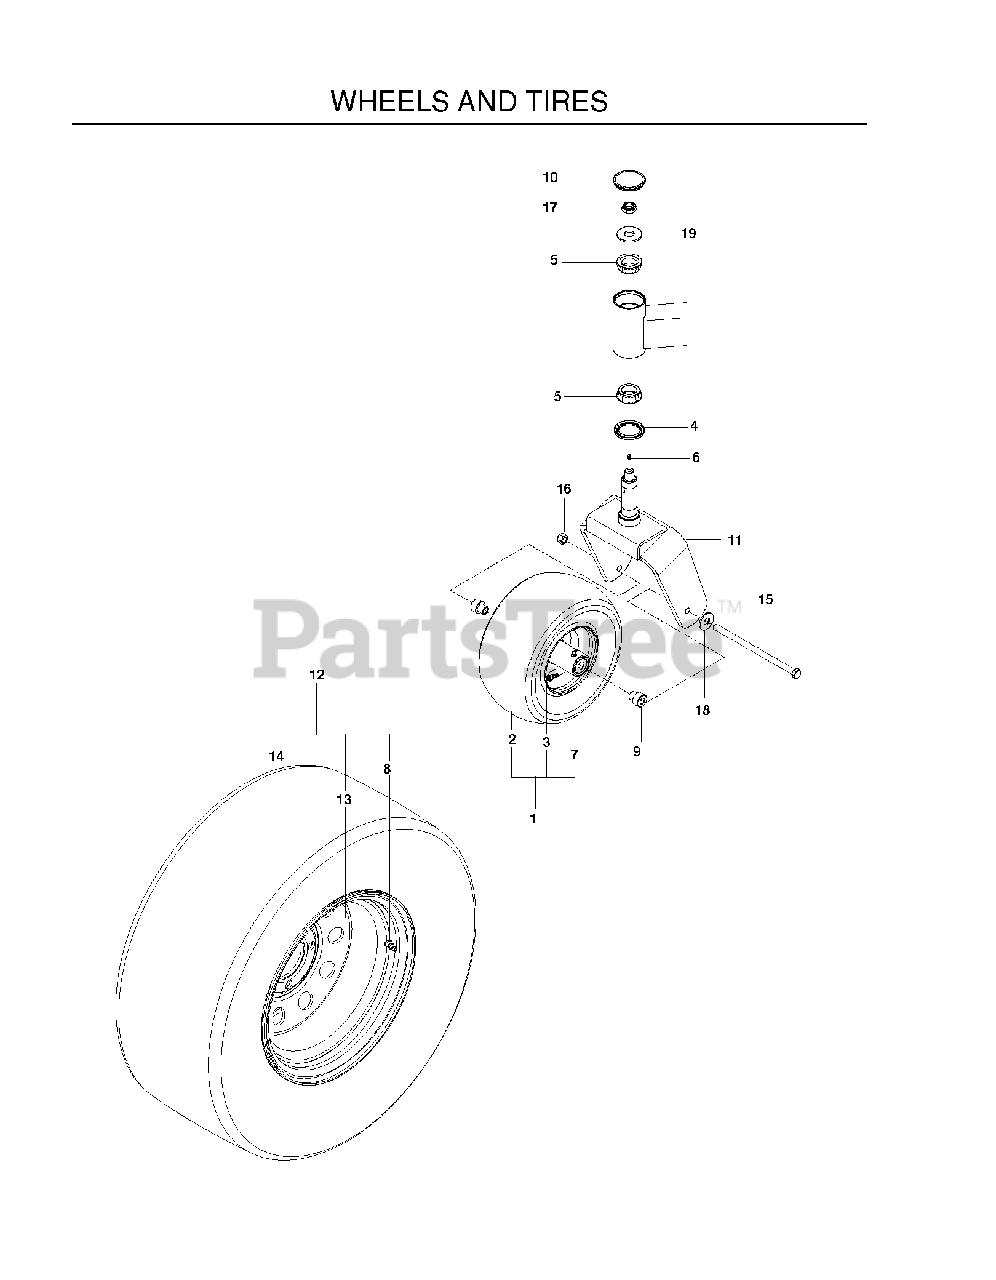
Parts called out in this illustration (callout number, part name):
1	FRONT TIRE ASSY
2	TIRE - SMOOTH 13X6.50-6
4	SEAL, BEARING
5	CONE, LM67048
7	ZERK
8	VALVE STEM TR-412
9	AXLE SPACER
11	FORK.CASTER.ORANGE
12	TIRE 23X8.5-12
13	RIM 12X7 .236 NEG OFFSET
14	TIRE - 23X8.5-12
15	HEX SCREW 1/2-13 X 9.5 GR5
16	NUT, 1/2-13 HEX FLG NYLOC ZD
17	NUT, 3/4-16 HEX THIN NYLOC ZD
18	WASHER 1/2" FLAT
19	WASHER, 3/4 HARDENED
